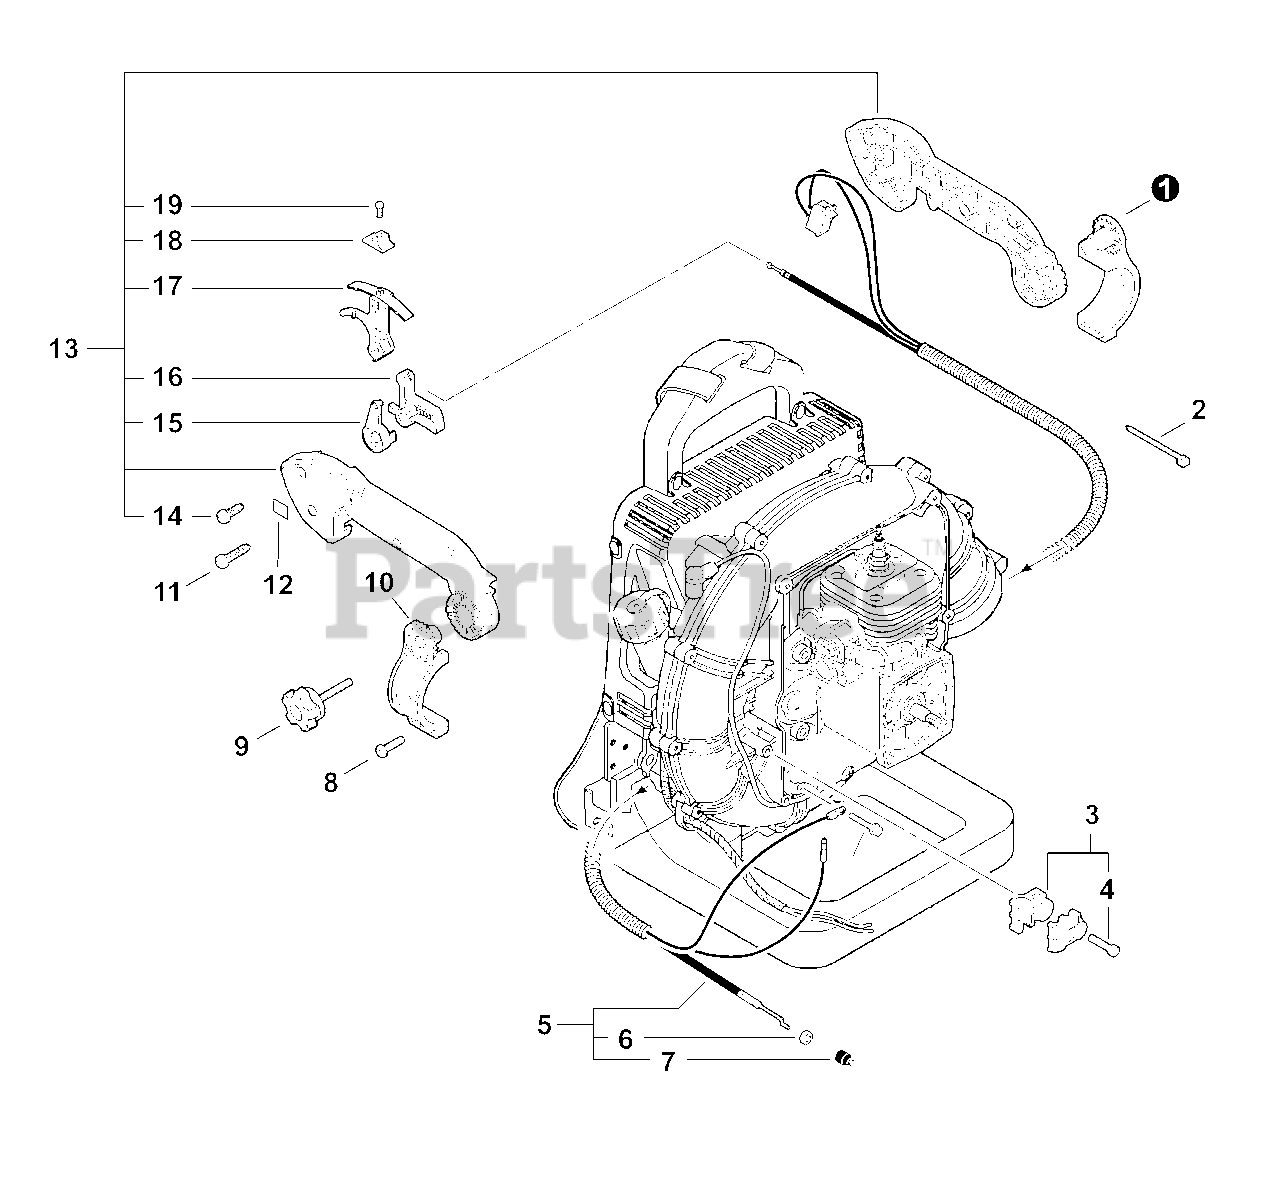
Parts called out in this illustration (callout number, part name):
1	BRACKET, HANDLE - RIGHT
2	TIE, CABLE - SMALL
3	CABLE BRACKET KIT
4	SCREW - 5×25 -- TAPPING
5	CONTROL CABLE ASSY
6	LOCKNUT - 6
7	CAP, DUST
8	SCREW - 5×20 -- TAPPING
9	THUMBSCREW
10	BRACKET, HANDLE - LEFT
11	SCREW - 5
12	LABEL - IDLE
13	CONTROL HANDLE ASSY
14	SCREW - 5×20
15	LEVER, THROTTLE
16	TRIGGER, THROTTLE
17	LEVER, THROTTLE CONTROL
18	KNOB, THROTTLE CONTROL
19	SCREW - 3×14
